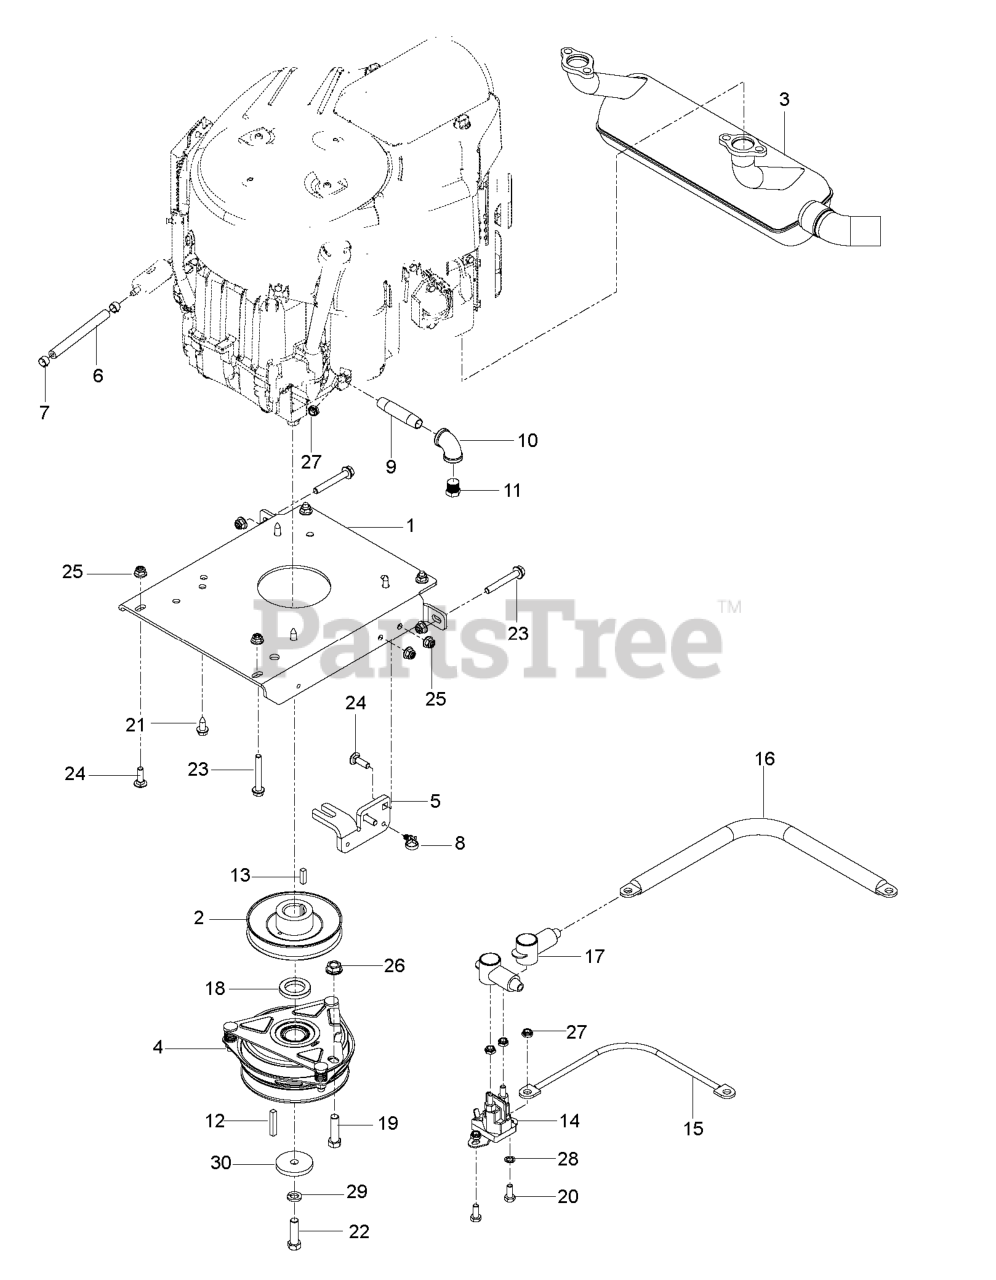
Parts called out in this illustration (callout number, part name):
1	PLATE.ENGINE.BLACK
2	PULLEY, ENGINE
3	MUFFLER, B&S CYCLONIC
4	CLUTCH, 150 FT/LBS
5	STOP, CLUTCH, OGURA
6	FUEL LINE 5"
7	HOSE CLAMP
8	TIE WRAP, 8-3/8", W/CLIP
9	PIPE NIPPLE 3/8 X 3
10	90 DEG.ELBOW 3/8NPT
11	PLUG, DRAIN 3/8 NPTF
12	KEY 1/4 SQ X 2
13	KEY 1/4 SQ X 1.0
15	GROUND WIRE (KAW)
16	CABLE POSITIVE
18	SPACER, .25 X 1.135 I.D.
19	HCS 7/16-14 X 1-1/4 GR 5 ZD
20	HCS 1/4C X 5/8
21	HHFS 3/8-16 X 1.0 THD FORMING
22	HCS 7/16F X 1 1/2
23	HHFS 5/16-18 X 2.25 GD 5
24	RHSNB 5/16C X 1
25	5/16-18 NYLOC FLANGE NUT
26	NUT 7/16C WHIZ
27	JAM NUT 1/4C (2 2 PW01)
28	WASHER 1/4 INT TOOTH
29	WASHER 7/16 LOCK
30	BLADE WASHER
